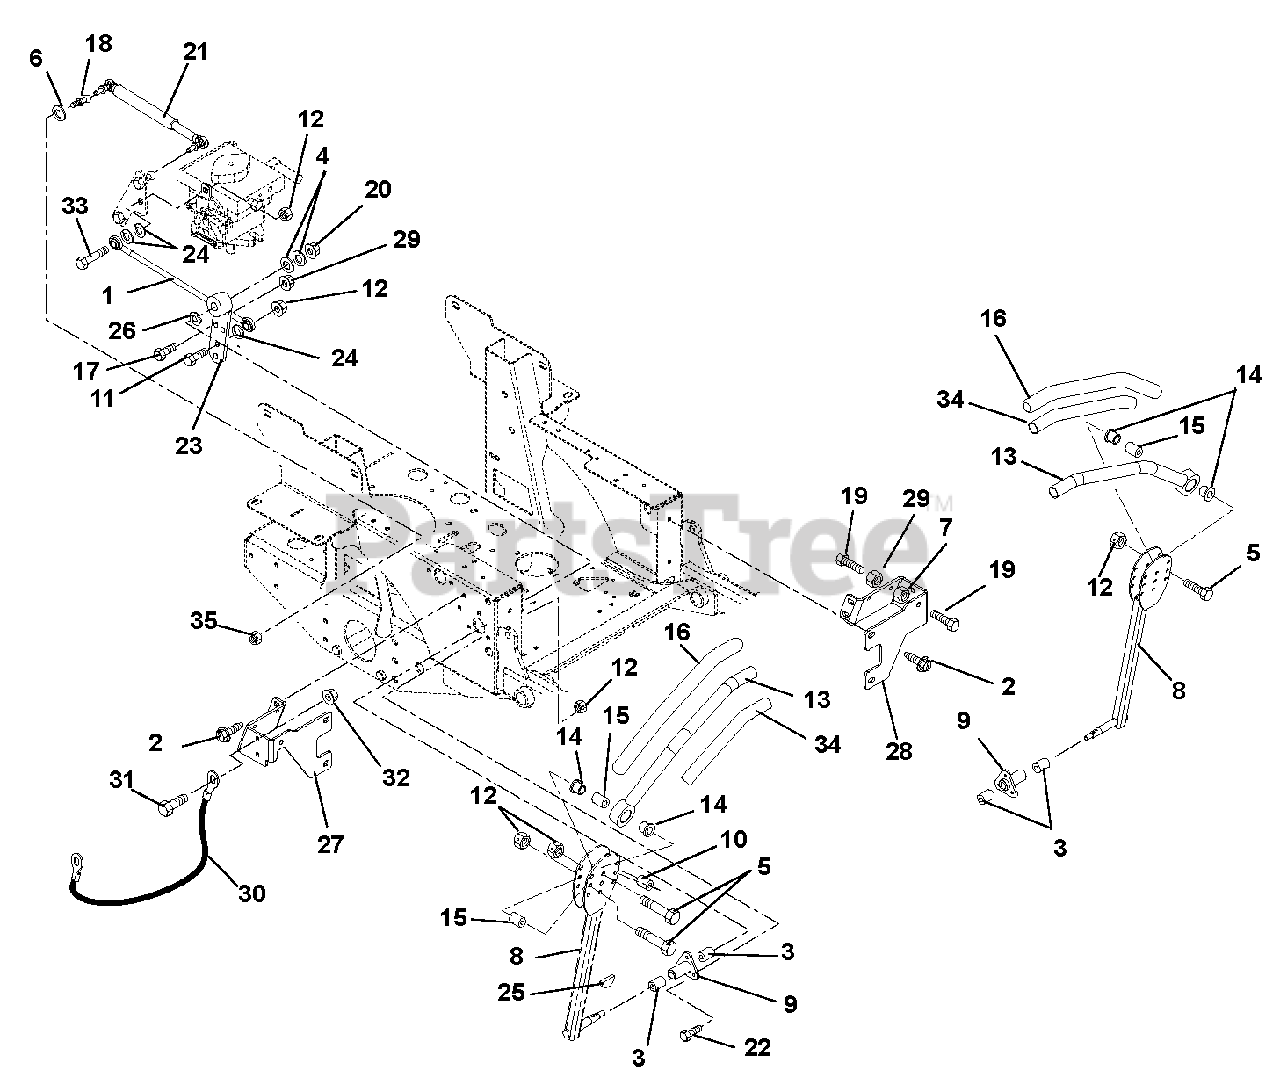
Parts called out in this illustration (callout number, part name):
1	Assembly, Steering Rod
2	Screw, Tapping .38-16 x .75 Hex Washer Head
3	Bushing .625 x .75 x .50
4	Washer, Flat Steel .406 x .812 x .065
5	Bolt, Hex .31-18 x 1.75 Grade 5
6	Washer, Flat Steel .344 x .065 YWZC
7	Nut, Hex Jam .375-16
8	Control Arm
9	Housing, Bushing
10	Bushing, Eccentric .31 x .75 x .97
11	Bolt, Hex .31-18 x 1.25
12	Nut, Nyloc Flange .375-16
13	Handle Weldment, Left Hand
14	Bushing, Flange Nylon .762 x 1.48 x .44
16	Grip, Handlebar
17	Bolt, Hex .375-16 x 1.75
18	Stud, Ball
19	Bolt, Hex .38-16 x 1.25
20	Nut, Nyloc Flange 3/8-16
21	Damper
22	Bolt, Hex .31-18 x 1.00
23	Weldment, Pivot Arm
24	Washer, Locking .31 x .078 Regular
25	Key, Woodruff .13 x .63
26	Wave Washer
27	Stop, Steering, Right Hand
28	Stop, Steering, Left Hand
29	Nut, Locking Jam Center .375-16
30	Cable, Hood
31	Bolt, Hex .25-20 x .75
32	Nut, Nyloc Flange .25-20
33	Bolt, Hex .31-18 x 1.50
34	Tube, .88ID x 1.00OD x 10.75
35	Nut, Top Lock .31-18
